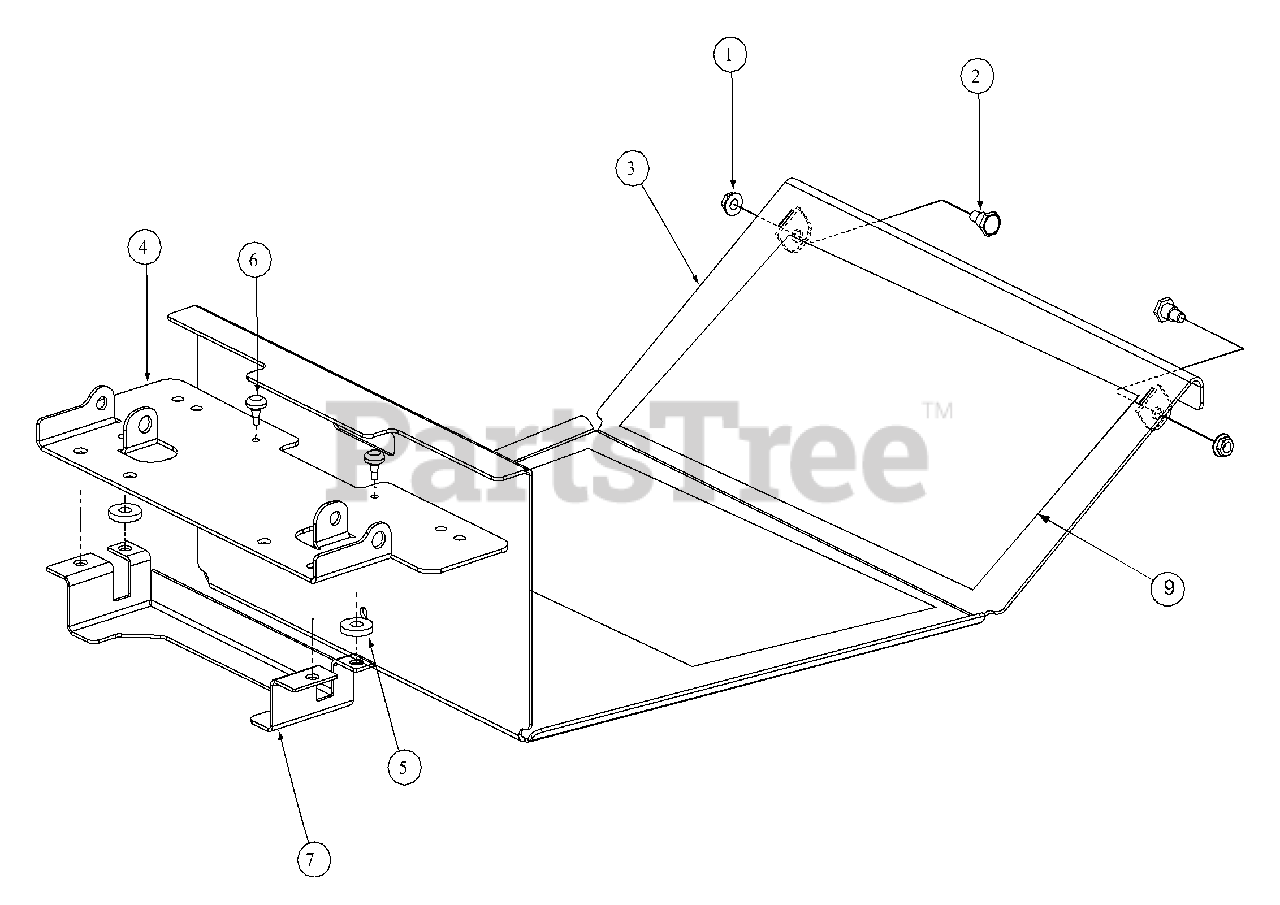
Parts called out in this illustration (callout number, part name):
1	Lock Nut, Hex Flange 5/16-18
2	Shoulder Screw, .435 x .350, 5/16-18
3	Floor Assembly Panel
4	Panel Seat
5	Washer
6	Rubber Bumper, .62 OD x .22 Thick
7	Seat Bracket Support
9	Abrasive Foot Pad
